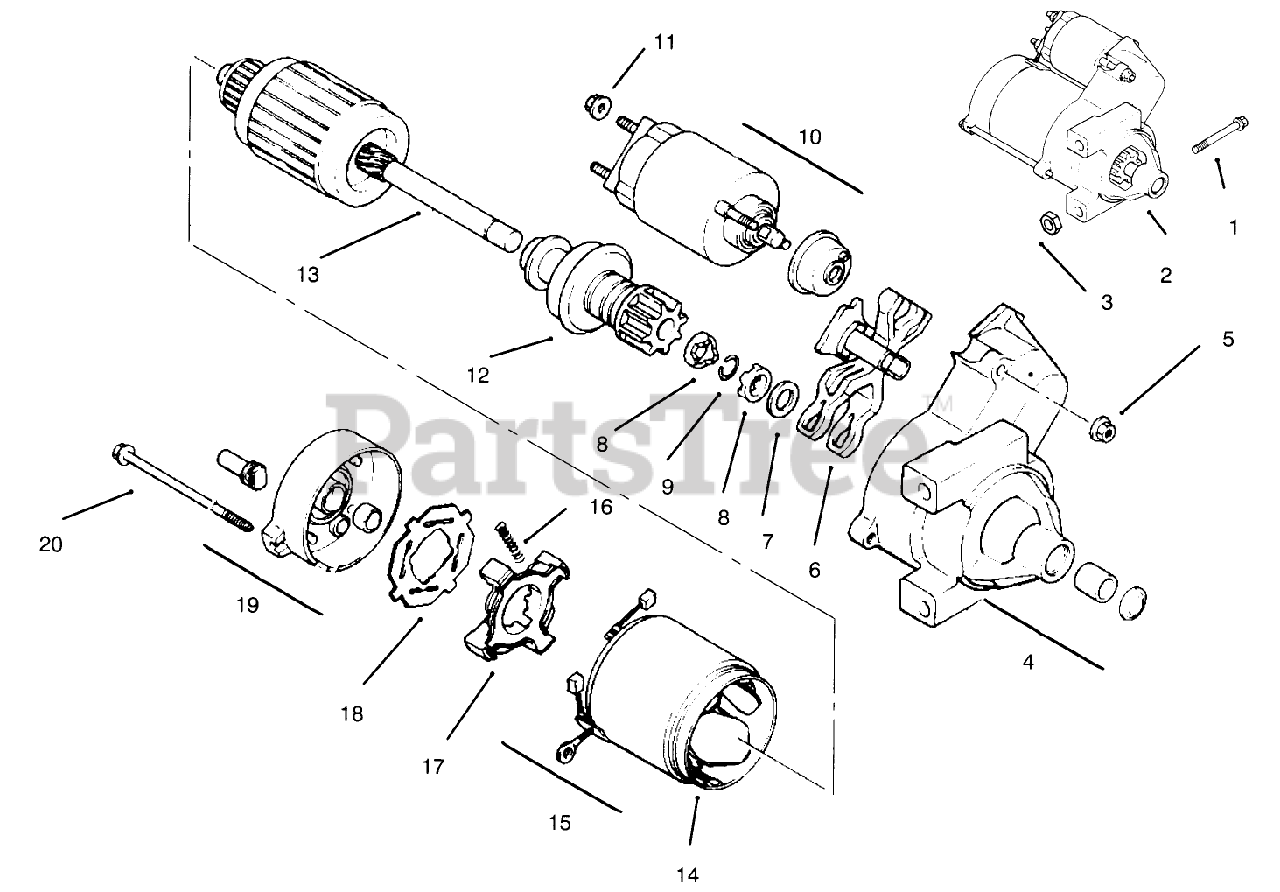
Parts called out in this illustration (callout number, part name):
2	Starter-Solenoid Shift (Incl. Ref. # 4-20)
4	Cap-Drive End
5	Nut Starter
6	Lever Starter Drive
7	Washer-Thrust
8	Nut-Stop Collar
9	Ring-Retainer
10	Solenoid
12	Drive-Pinion
13	Armature-Starter
15	Kit-Brush (Incl. Ref. # 16)
16	Spring-Brush
17	Holder-Brush
18	Insulator
19	Cap-Commutator End
